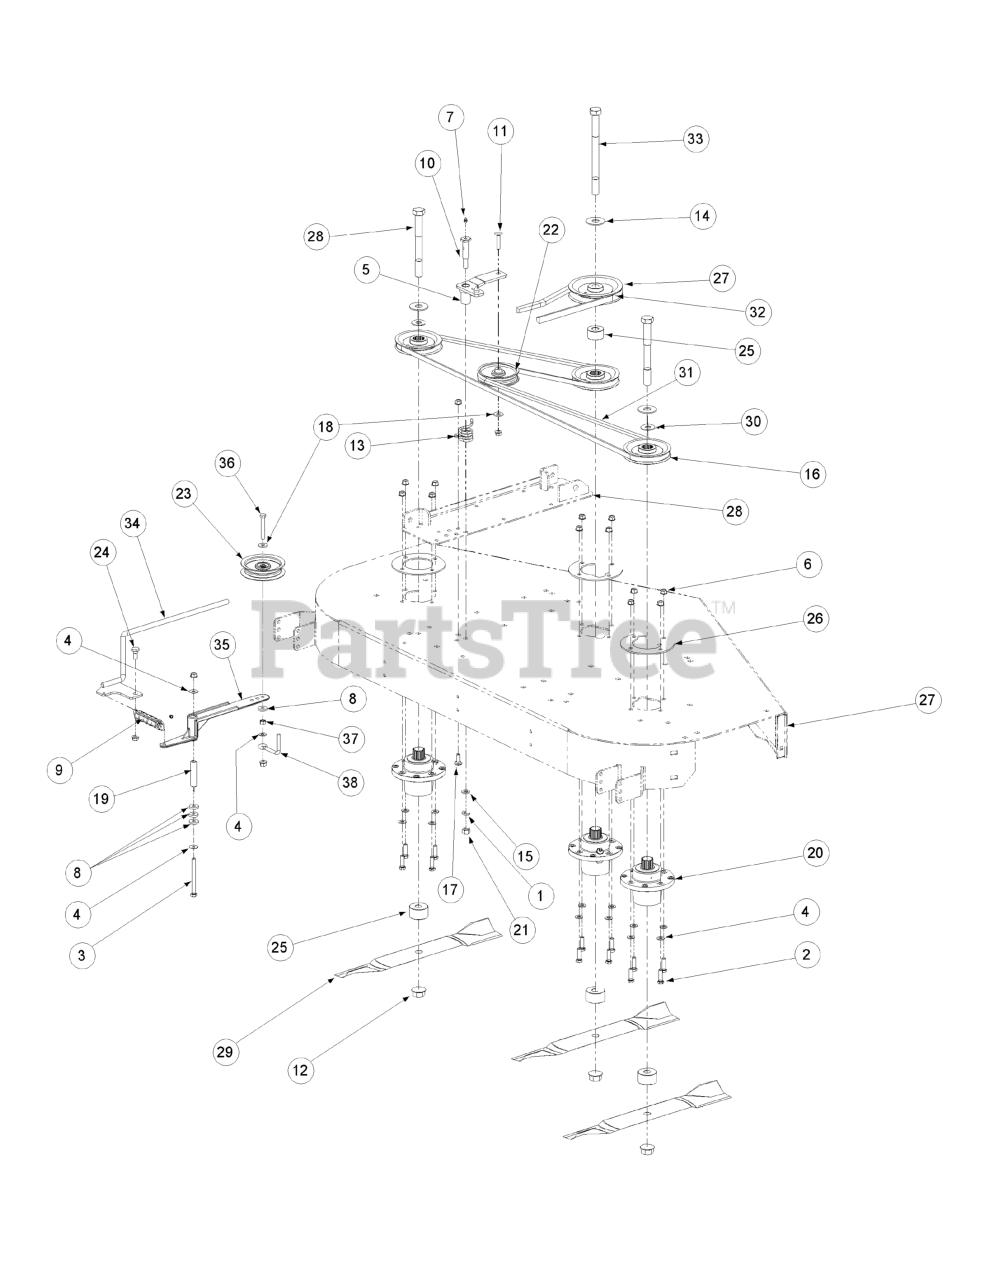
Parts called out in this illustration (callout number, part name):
1	Lock Washer, 7/16
2	Hex Cap Screw, 3/8-16 x 1-1/2
3	Hex Cap Screw, 3/8-16, 4.00
4	Flat Washer, 3/8
5	Idler Arm Casting, Deck Spindle
6	Flange Lock Hex Nut, 3/8-16
7	Grease Fitting, 1/4-28 x 3/16
8	Idler Washer
9	Extension Spring, .98 x OD x5.000
10	Shoulder Screw, 7/16-14
11	Hex Carriage Screw, 3/8-16, 1.75
12	Flange Hex Nut, 3/4-16
13	Torsion Idler Spring
14	Flat Washer, .781 ID 2.00 OD, .105
15	Flat Washer, .469 ID, .875 OD, .15
16	V-Pulley, 5.00 OD
17	Carriage Bolt, 3/8-16 x 1
18	Flat Washer, .406 ID, 1.0 OD, .105
19	Spacer, .39 ID x .625 OD x 2.75
20	Aluminum Spindle Assembly
21	Hex Nut, 7/16-14
22	Flat Pulley
23	Idler Pulley, 4.06 OD
24	Shoulder Screw, .50 x .27 Lg., 3/8-16
25	Spacer, .760 ID x 2.00 OD x .925
26	Aluminum Spindle Support Plate
27	V-Pulley, Cast, 6.360 OD
28	Hex Cap Screw, 3/4-16, 7.00
29	Hi-Lift Blade, 21.0, 0.756 ID
30	Spacer .812 ID x .218 LG
31	V-Belt, A Section x 122.3
32	V-Belt, B Section x 147.4
33	Hex Cap Screw, 3/4-16, 9.00
34	Spring Tension Rod Assembly
35	Idler Arm Assembly, Flat Top Bearing
36	Hex Cap Screw, 3/8-16 x 2.50
37	Hex Nut, 3/8-16
38	Belt Guide
